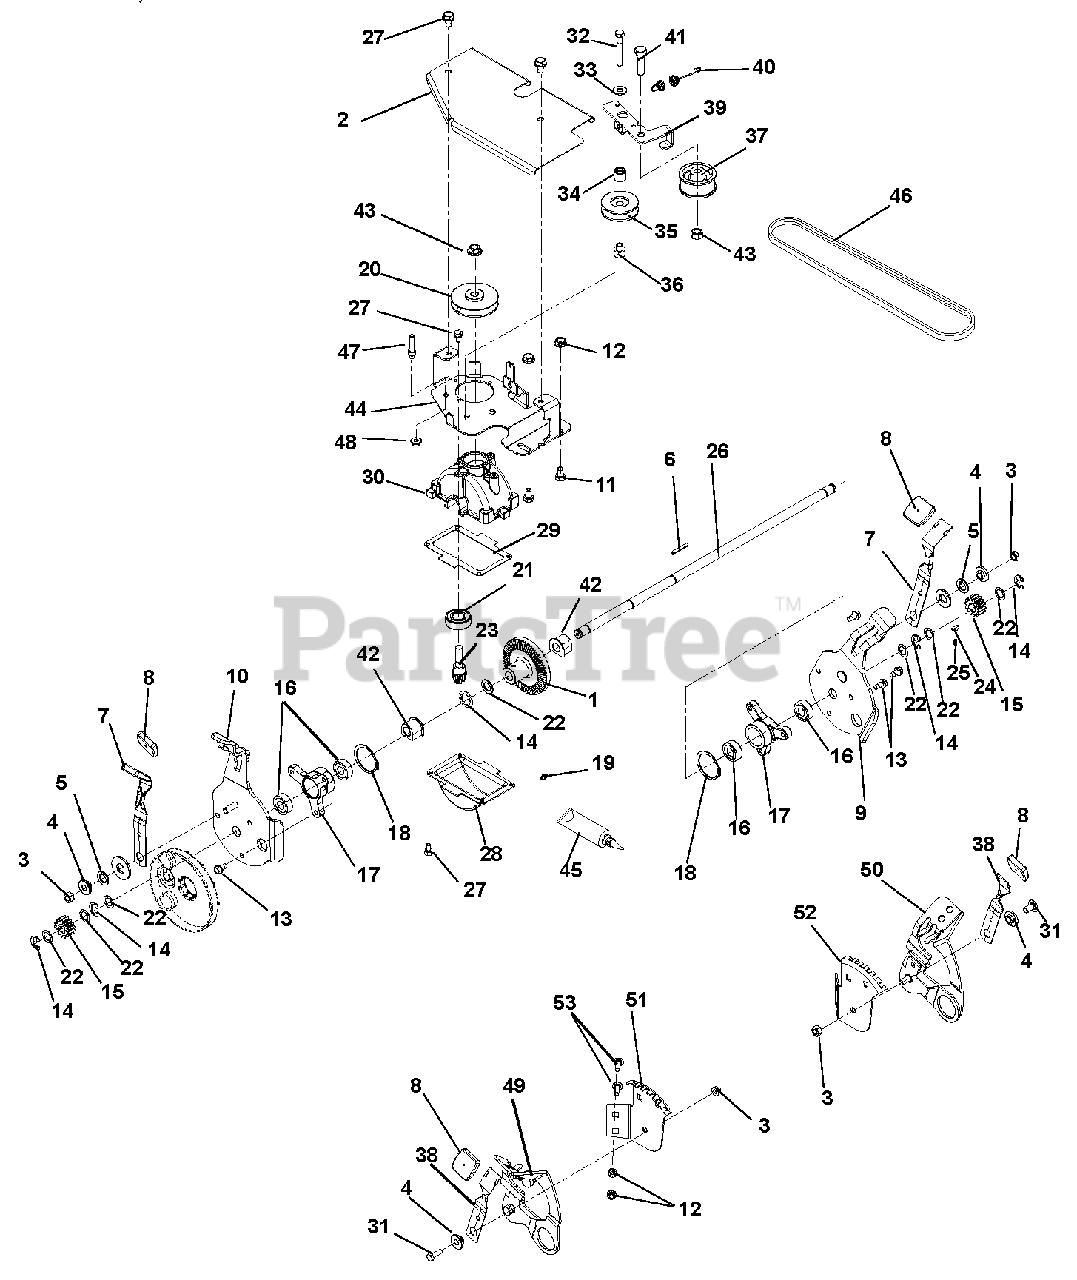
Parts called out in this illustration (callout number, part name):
1	Gear, Reduction
2	Cover, Transmission
3	Nut, Locking, Center .31-18
4	Bushing, Flange .265 x .437 x .250 x .750
5	Washer, Flat, Steel .52 x .827 x .062
6	Key, 1/8 x 1/8 x 1.0
7	Lever, Height Adjustment
9	Weldment, Height Adjuster RHS
10	Weldment, Height Adjuster LHS
11	Bolt, Hex .31-18 x .50
12	Nut, Locking, Top, Flange .31-18
13	Screw, Tapping .25-20 x .50 Hex Washer Head
14	Ring, Retaining, Internal .50 x .049
15	Pinion, WBLM Drive
16	Bearing, .375 x .875 x .281
17	Bushing, Height Adjuster Pivot
18	Ring, Retaining External 1.387 x .050
19	Fitting, Lube .25-28 x .256
20	Half, Transmission Input Pulley
21	Bearing, Ball .625 x 1.375 x .43
22	Washer, .500 x .750 x .020 Thrust
23	Pinion, Gearbox Input
24	Key, Woodruff .125 x .50 x .20
25	Spring, .134 x .186 x .144 Compression
26	Shaft, Transmission Output
27	Screw, Tapping 10-24 x .375 Hex Washer Head
28	Sump, Gearbox
29	Gasket, Transmission
30	Casting, WBLM Gear Box
31	Bolt, Hex .31-18 x 1.00
32	Bolt, Hex .25-20 x 2.25 Grade 8
33	Washer, Flat Steel .328 x 1.0 x .094
34	Spacer, .390 x .75 x .189
35	Idler, 3L Front Side .38 x 1.875
36	Spacer, Idler Pulley
37	Idler, Flat 1.875OD x .75 Wide
38	Front Height Adjustment Lever
39	Arm, Transmission Idler
40	Spring, Tension .051 x .60 x 2.25
41	Bolt, Hex .38-16 x 1.25
42	Bushing, Transmission Output Shaft
43	Nut, Locking, Top, Flange .38-16
44	Bracket, Transmission Control
45	Lubricate
46	V-Belt 3L 35.98
47	Finger, Belt
48	Nut, Locking, Flange .250-20
49	Right Hand Adjuster Bracket
50	Left Hand Adjuster Bracket
51	Front Quadrant, Right Hand
52	Front Quadrant, Left Hand
53	Bolt, Round Head Square Neck .31-18 x 1.00
